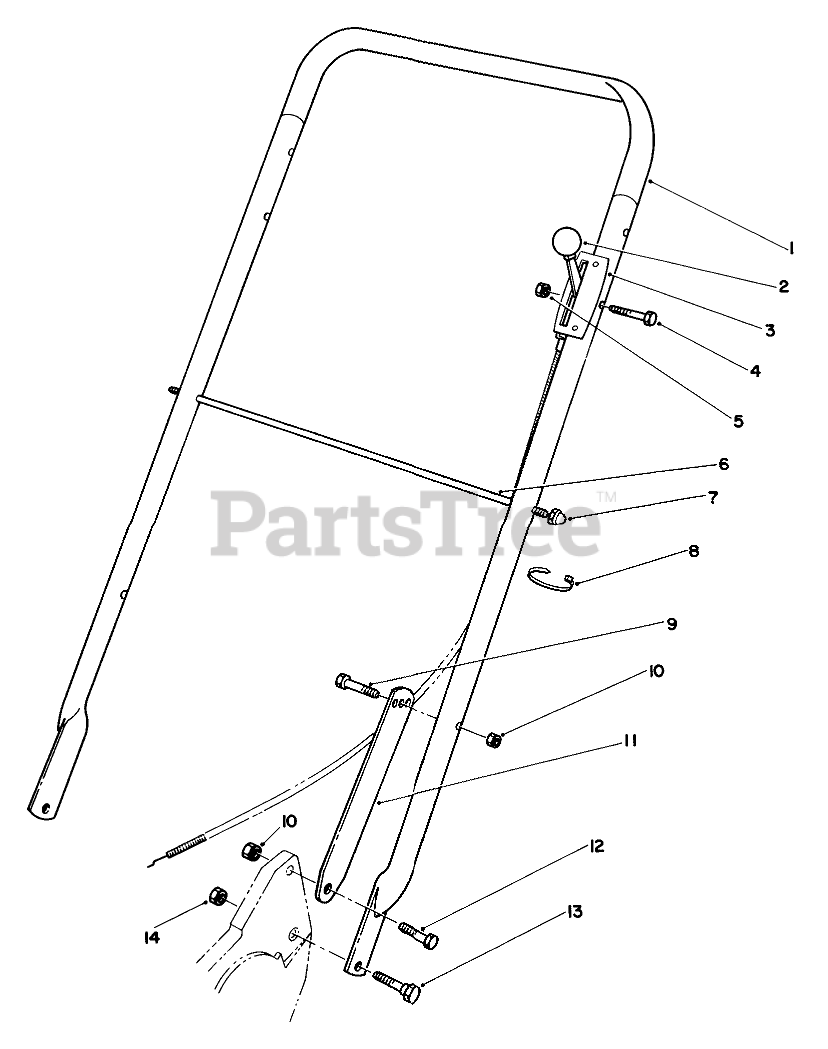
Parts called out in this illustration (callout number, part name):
1	HANDLE
2	KNOB-CONTROL
3	THROTTLE CONTROL
4	SCREW-HH
5	NUT-LOCK, NI
6	ROD-SUPPORT, BAG
7	NUT-CAP
8	TIE-CABLE
9	SCREW-HH
10	NUT-LOCK, NI
11	Latch-Handle
12	SCREW-HH
13	SCREW-SHOULDER
14	NUT-LOCK, CONE
